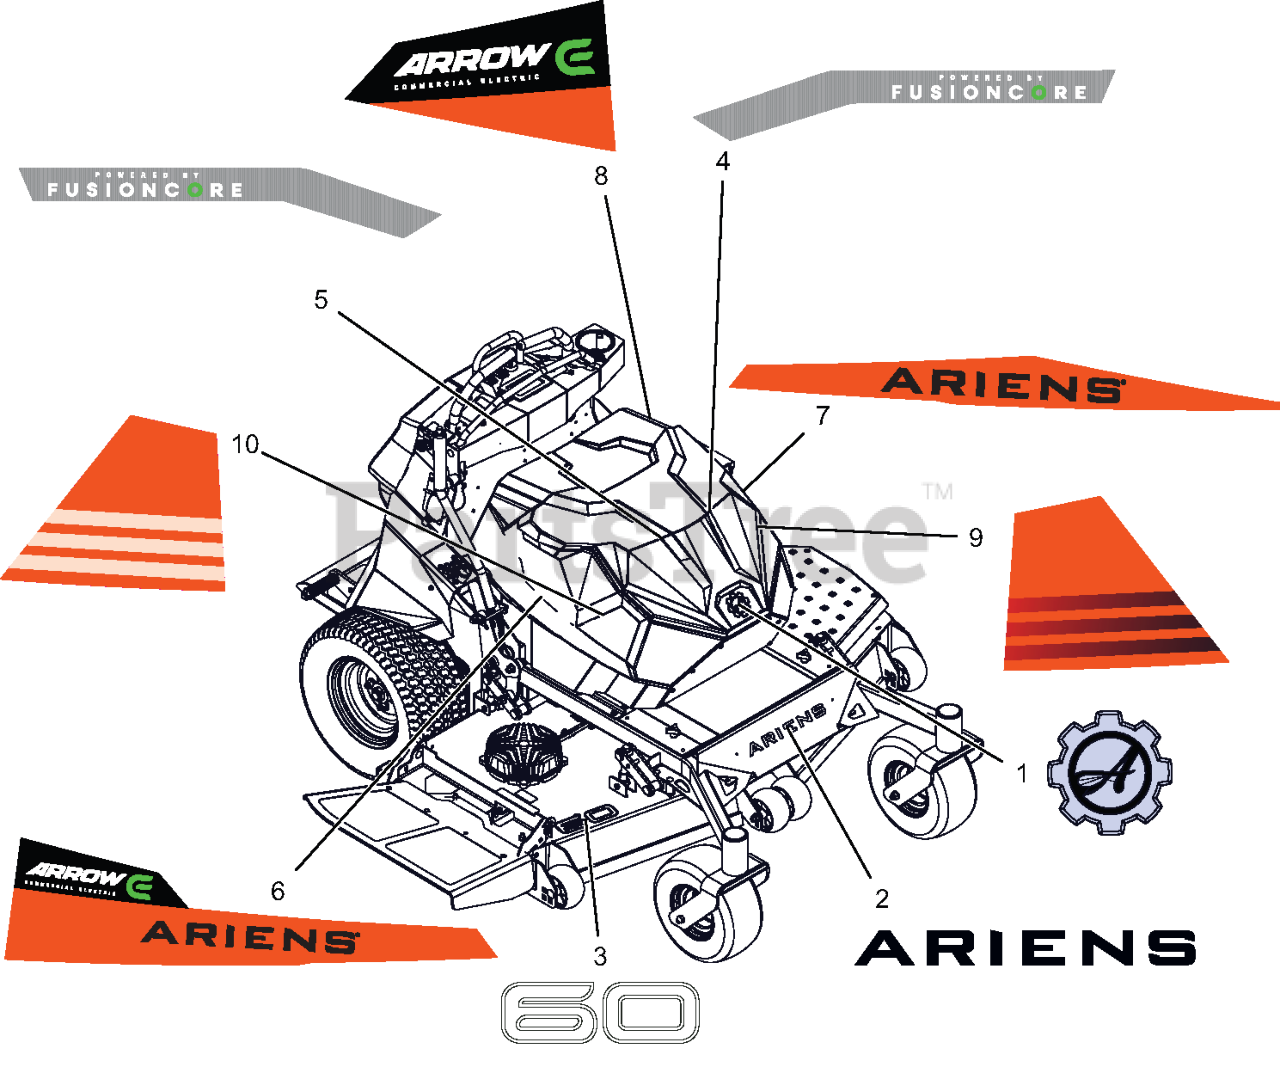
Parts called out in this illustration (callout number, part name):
1	DECAL- ARIENS GEAR BADGE
2	DECAL, ARIENS - 12.0"
3	DECAL, DECK - 60"
4	DECAL, ARROW E FUSION CORE RH
5	DECAL, ARROW E FUSION CORE LH
6	DECAL, ARROW E SIDE RH
7	DECAL, ARROW E SIDE LH
8	DECAL, ARROW REAR HOOD PSEV
9	DECAL, ARROW E FRONT HOOD
10	DECAL, ARROW E RH FENDER UPPER
